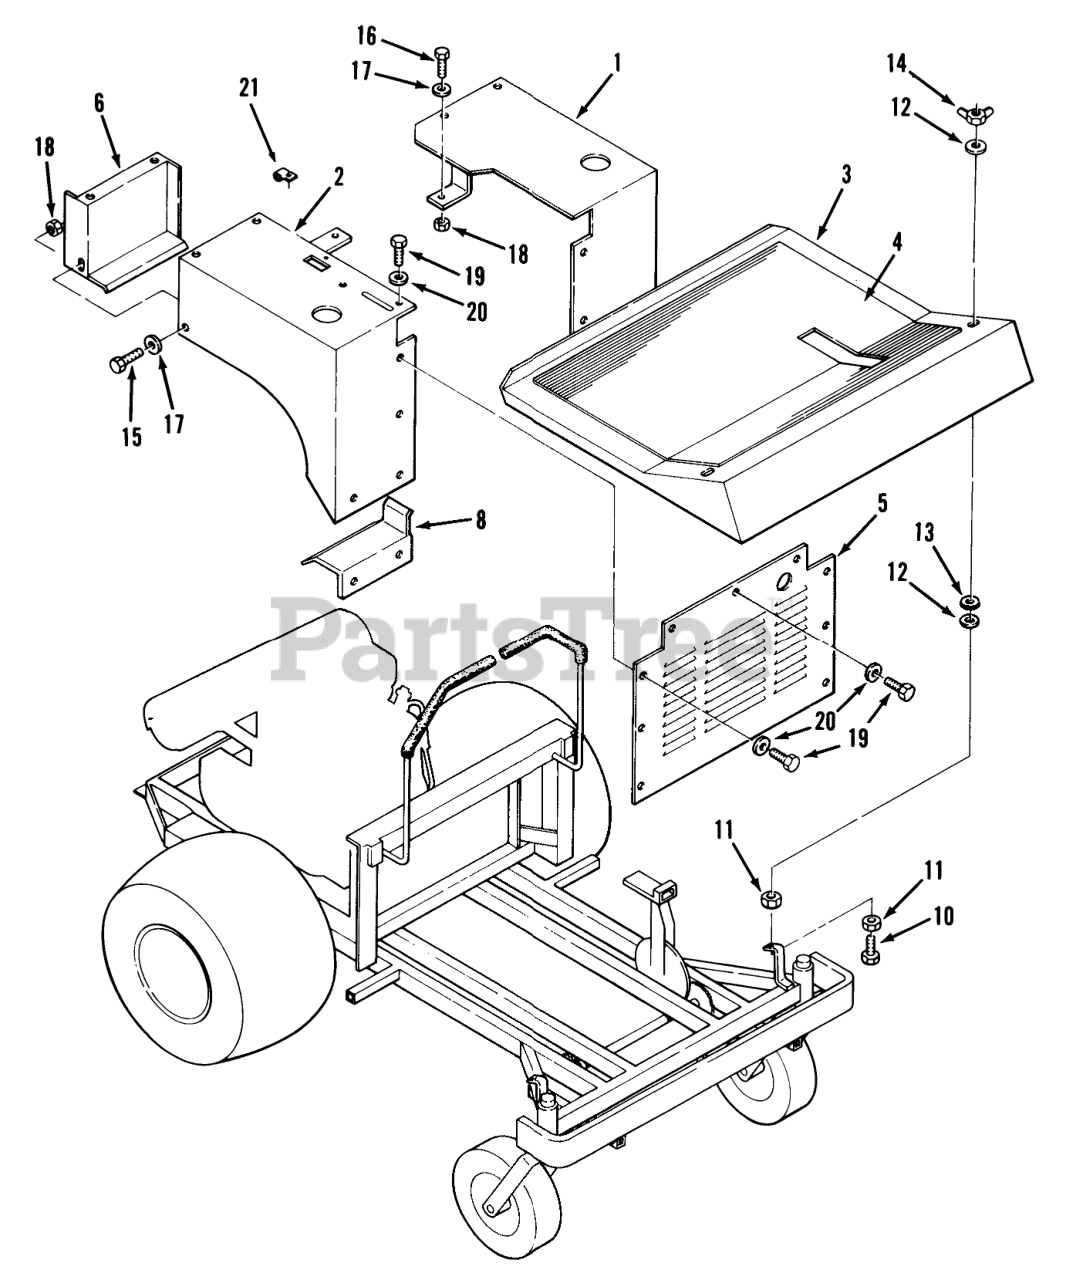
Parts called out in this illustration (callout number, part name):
1	Fender LH
2	ASS'Y-FENDER R.H. R
3	Floor Pan
4	Black Carpet
5	Front Panel
6	Bracket-Fender Rear RH
8	Bracket-Fender Frt RH
10	Full Thread Bolt 5/16 x 1-1/2
11	Nut
12	Washer
13	WASHER
14	WING NUT
15	H H C S
16	Bolt
18	Nut
19	Bolt
20	WASHER
21	J-CLIP
